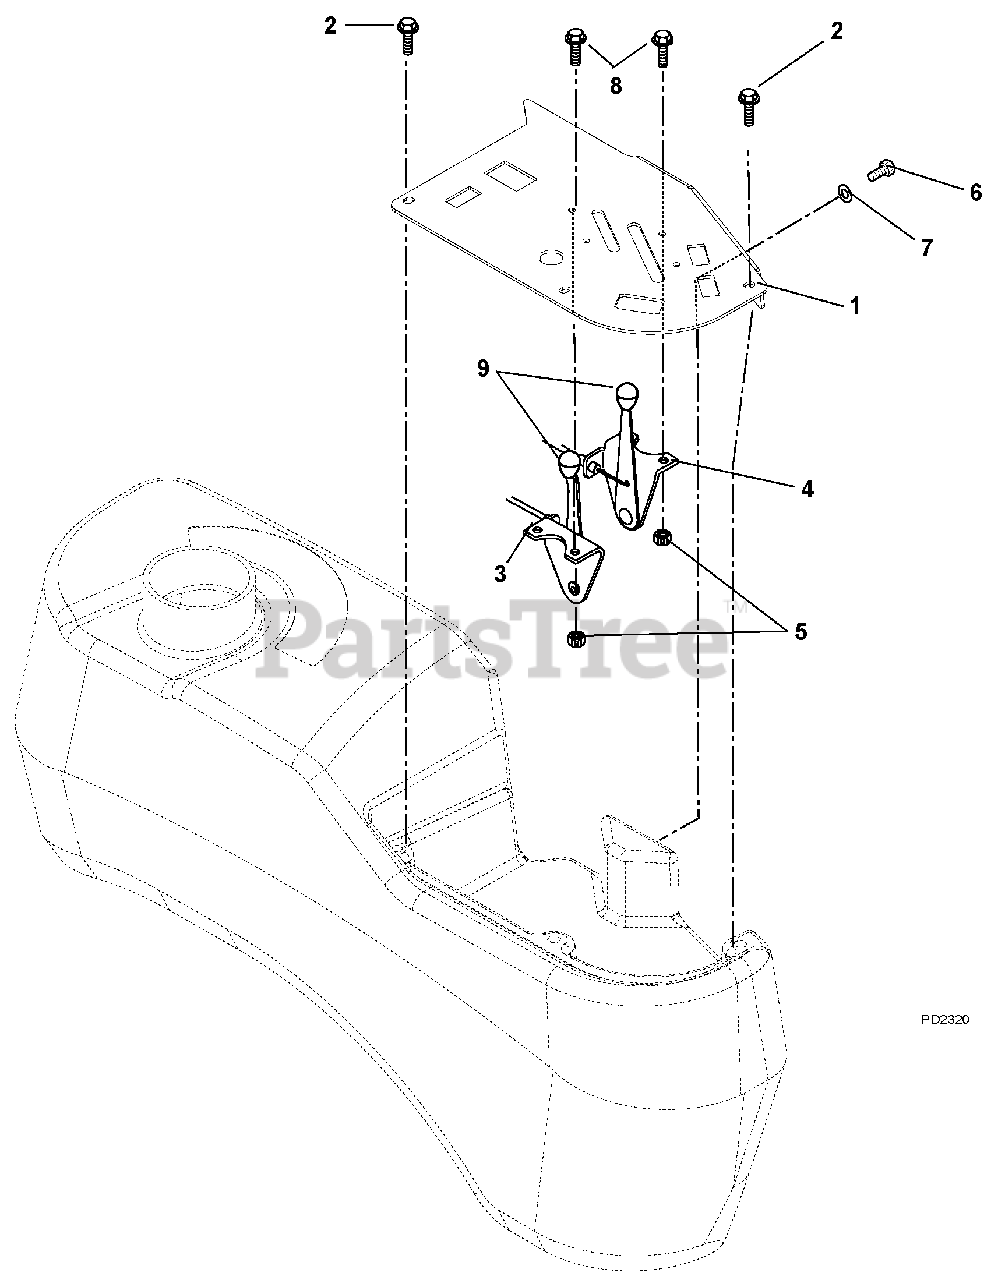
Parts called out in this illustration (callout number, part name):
1	Panel, Control
2	Screw, Machine 10-24 x .38 Hex Washer Head, Stainless
3	Throttle, Control
4	Choke Control
5	Nut, Locking Nylon 10-24 With Insert
6	Bolt, Hex .31-18 x .75 Grade 5
7	Washer, Flat Steel .38 x .875 x .083
8	Screw, Machine 10-24 x .50 Hex Washer Head
9	Knob, Control Black .38-16 x .62
